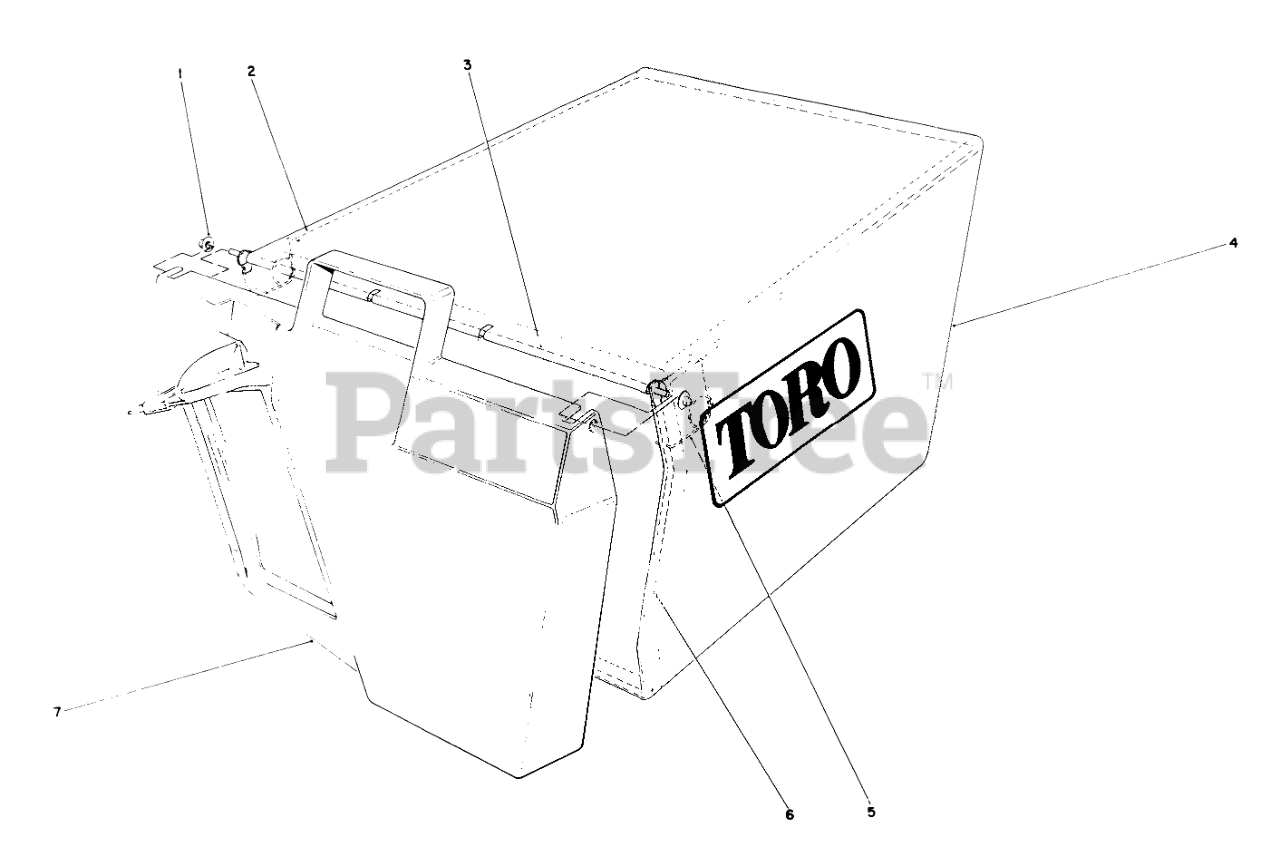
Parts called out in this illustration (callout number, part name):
1	NUT-PUSH
3	HINGE-DOOR, BAG
4	BAG-GRASS
5	SPRING
6	FRAME-BAG
7	DOOR-BAG
